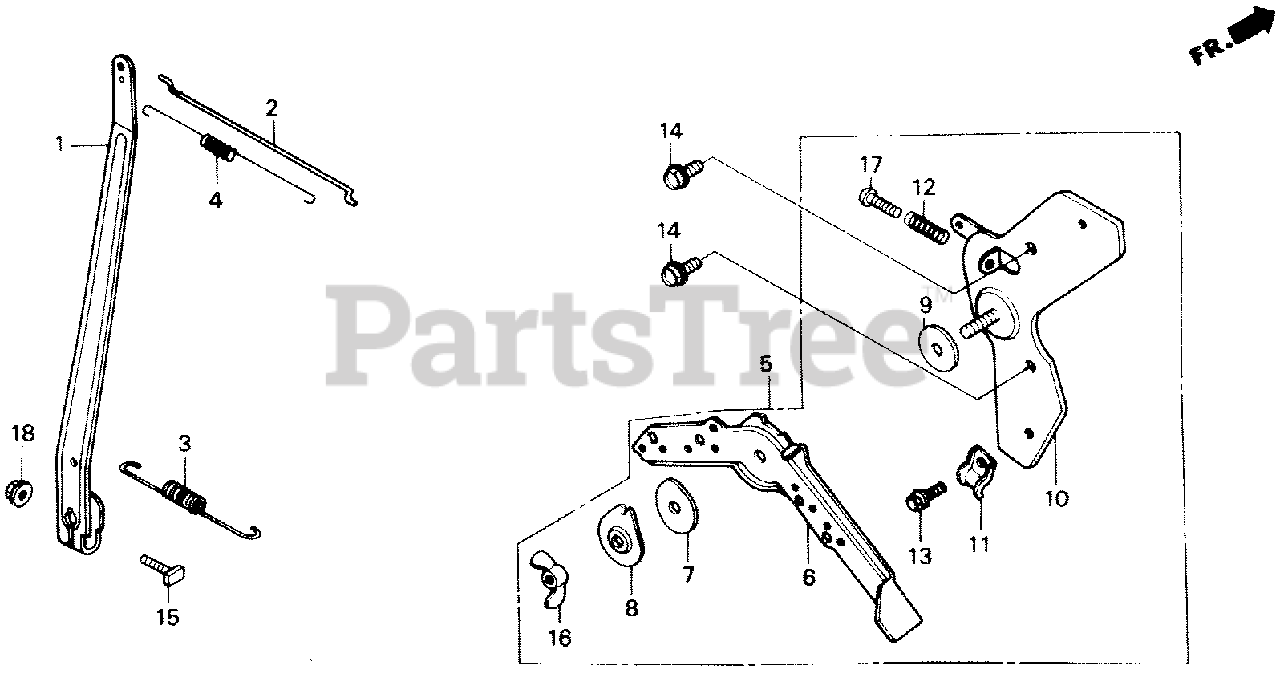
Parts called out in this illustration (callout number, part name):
1	ARM, GOVERNOR
2	ROD, GOVERNOR
3	SPRING, GOVERNOR
4	SPRING, THROTTLE RETURN
5	CONTROL ASSY.
6	LEVER, CONTROL
7	SPRING, LEVER
8	WASHER, CONTROL LEVER
9	SPACER, CONTROL LEVER
10	BASE, CONTROL LEVER
11	HOLDER, CONTROL CABLE
12	SPRING, CONTROL ADJUSTING
13	BOLT, FLANGE (5X10)
14	BOLT, FLANGE (6X12) (CT200)
15	BOLT, GOVERNOR ARM
16	WINGNUT (6MM)
17	SCREW, PAN (5X22)
18	NUT, FLANGE (6MM)
